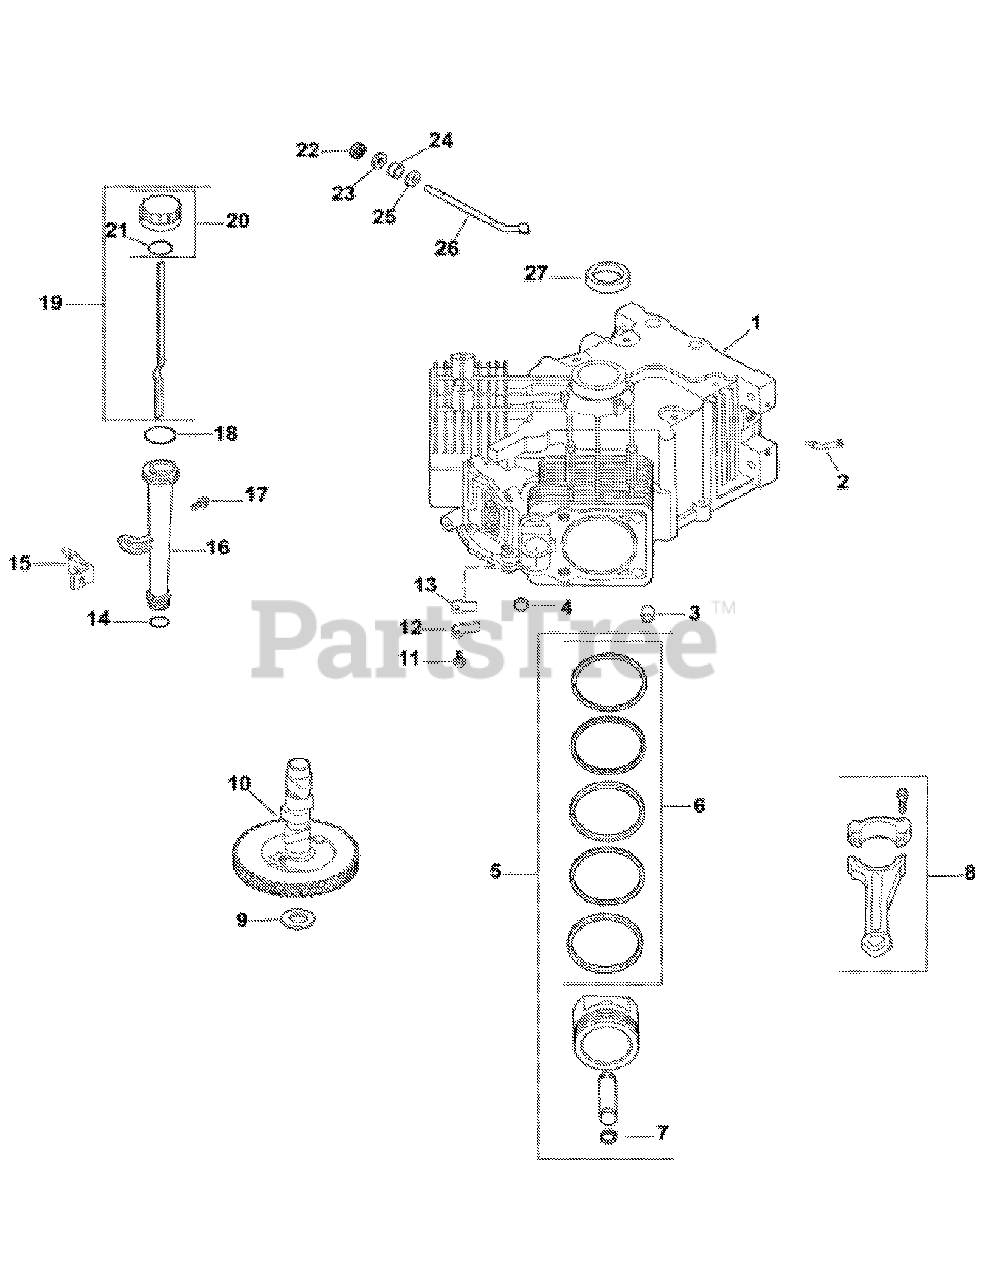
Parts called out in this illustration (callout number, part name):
3	Locating Pin
4	Cup Plug
5	Piston w/Ring Set (Std.)
5	Piston w/Ring Set (.08)
5	Piston w/Ring Set (.25)
5	Piston w/Ring Set (.50)
6	Ring Set (Std. & .08)
6	Ring Set (.25)
6	Ring Set (.50)
7	Piston Pin Retainer
8	Connecting Rod (Std.)
8	Connecting Rod (.25)
9	Camshaft Shim-Red
9	Camshaft Shim-Black
9	Camshaft Shim-White
9	Camshaft Shim-Blue
9	Camshaft Shim-Yellow
9	Camshaft Shim-Green
9	Camshaft Shim-Gray
10	Camshaft
11	Hex Flange Screw
12	Reed Retainer
13	Breather Reed
14	Lower Oil Fill Tube O-Ring
15	Oil Fill Tube Bracket
16	Oil Fill Tube
17	Hex Flange Screw
18	Upper Oil Fill Tube O-Ring
19	Dipstick Assembly
20	Oil Fill Cap Kit
21	Dipstick O-Ring
22	Ring Retainer
23	Plain Washer
24	Governor Cross Shaft Seal
26	Governor Cross Shaft
27	Front Oil Seal
